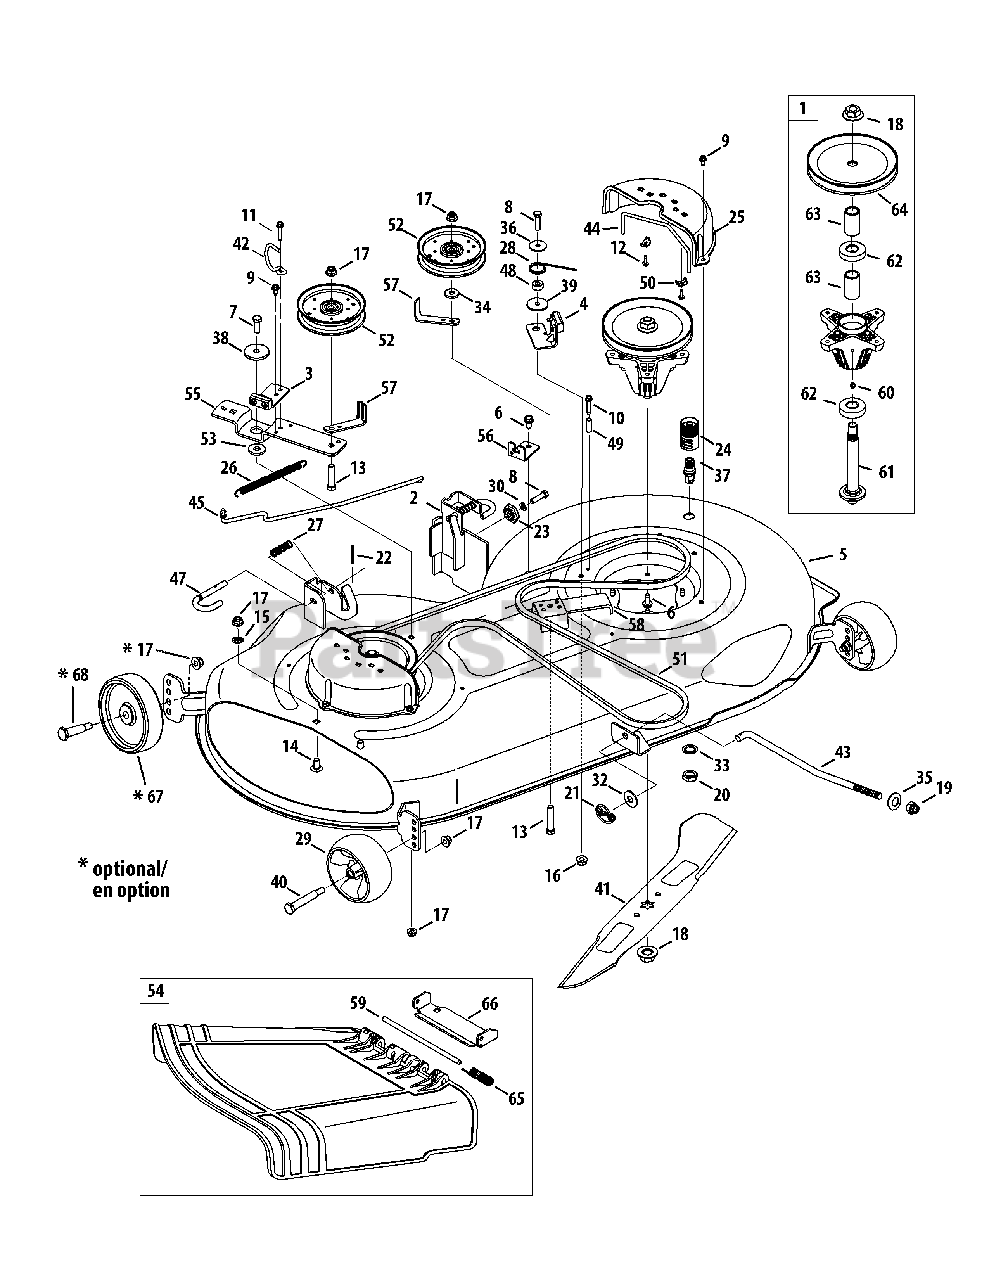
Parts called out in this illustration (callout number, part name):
1	Pulley Spindle Ass’y 6.93 dia.
2	Deck Hanger Bracket Ass'y LH
3	Deck Brake Assembly
4	Deck Brake Assembly
5	Deck Ass'y, 46" (decks w/2 wheel mounts)
6	S-Tapp Screw 5/16-18 x .75
7	Hex. Hd. Cap Screw. 3/8-16 x 1.0 Gr. 5
8	Hex Wash Tap Screw 5/16-18 x 1.25
9	Hex Wash S-Tapp Screw 1/4-20 x .50
10	Hex Wash HD Bolt 1/4-20 x 1.50" Lg.
11	Hex Hd. TT Screw. 1/4-20 x .75
12	Screw, B, #10-16 x .625
13	Hex. Hd. Cap Screw. 3/8-16 x 2.0 Gr. 5
14	Carriage Bolt 3/8-16 x .75 Gr. 1
15	Push Nut, 3/8
16	Hex Flange Locknut 5/16-18 Gr. F, Nylon
17	Hex Flange Locknut 3/8-16 Gr. F Nylon
18	Hex Flange Locknut 5/8-18
19	Flexloc Nut 1/2-13
20	Hex Nut M16-1.5 DIN 936
21	Lynch Pin
22	Cotter Pin .08 x 1.25
23	Deck Gear Ad juster
24	Water Nozzle Adapter
25	Belt Cover
26	Extension Spring .62 dia. x 6.12 Lg.
27	Compression Spring .535 x 1.751
28	Torsion Spring .992 ID x 1.17 OD
29	Deck Wheel 5.0 Dia.
30	L-Wash 5/16 ID
32	Flat Washer .531 x 1.25 x .100
33	L-Washer Internal
34	Flat Washer .385 ID x .870 OD x .092
35	Cupped Washer .63 x 1.25 x .18
36	Flat Washer .330 ID x 1.25 OD x .06
37	Deck Water Nozzle
38	Shoulder Spacer .8540 x .200
39	Shoulder Spacer
40	Shoulder Bolt .496 x 2.5, 3/8-16
41	Blade, 23.23", 2-in-1
42	Belt Keeper Rod
43	Deck Lift Rod
44	Belt Keeper Rod
45	Brake Control Rod
47	Deck Release Rod
48	Spacer .315 x .750 x .375
49	Spacer .260 x .375 x 1.030 Lg.
50	Cas ing Clamp
51	V-Belt
52	Idler Pulley w/Flange 4.25 Dia
53	Flat Washer .385 ID x 1.0 OD x .030
54	Side Dis charge Chute Assembly
55	Idler Pivot Bracket
56	Deck Cable Engagement Bracket
57	Belt Guard Pulley Bracket
58	Deck Idler Support Bracket
59	Hinge Pin .3125 diam. x 7.96" Lg.
60	Fitting
61	Spindle Shaft 6.11" Lg.
62	Ball Bearing .787 x 1.85 x .551
63	Spacer .792 x 1.060 x 1.860
64	Deck Pulley 6.93 Dia.
65	Torsion Spring .44 ID x 2.0
66	Chute Bracket (46")
67	Deck Wheel 5.0 x 1.38
68	Shoulder Bolt .496 x 1.5
